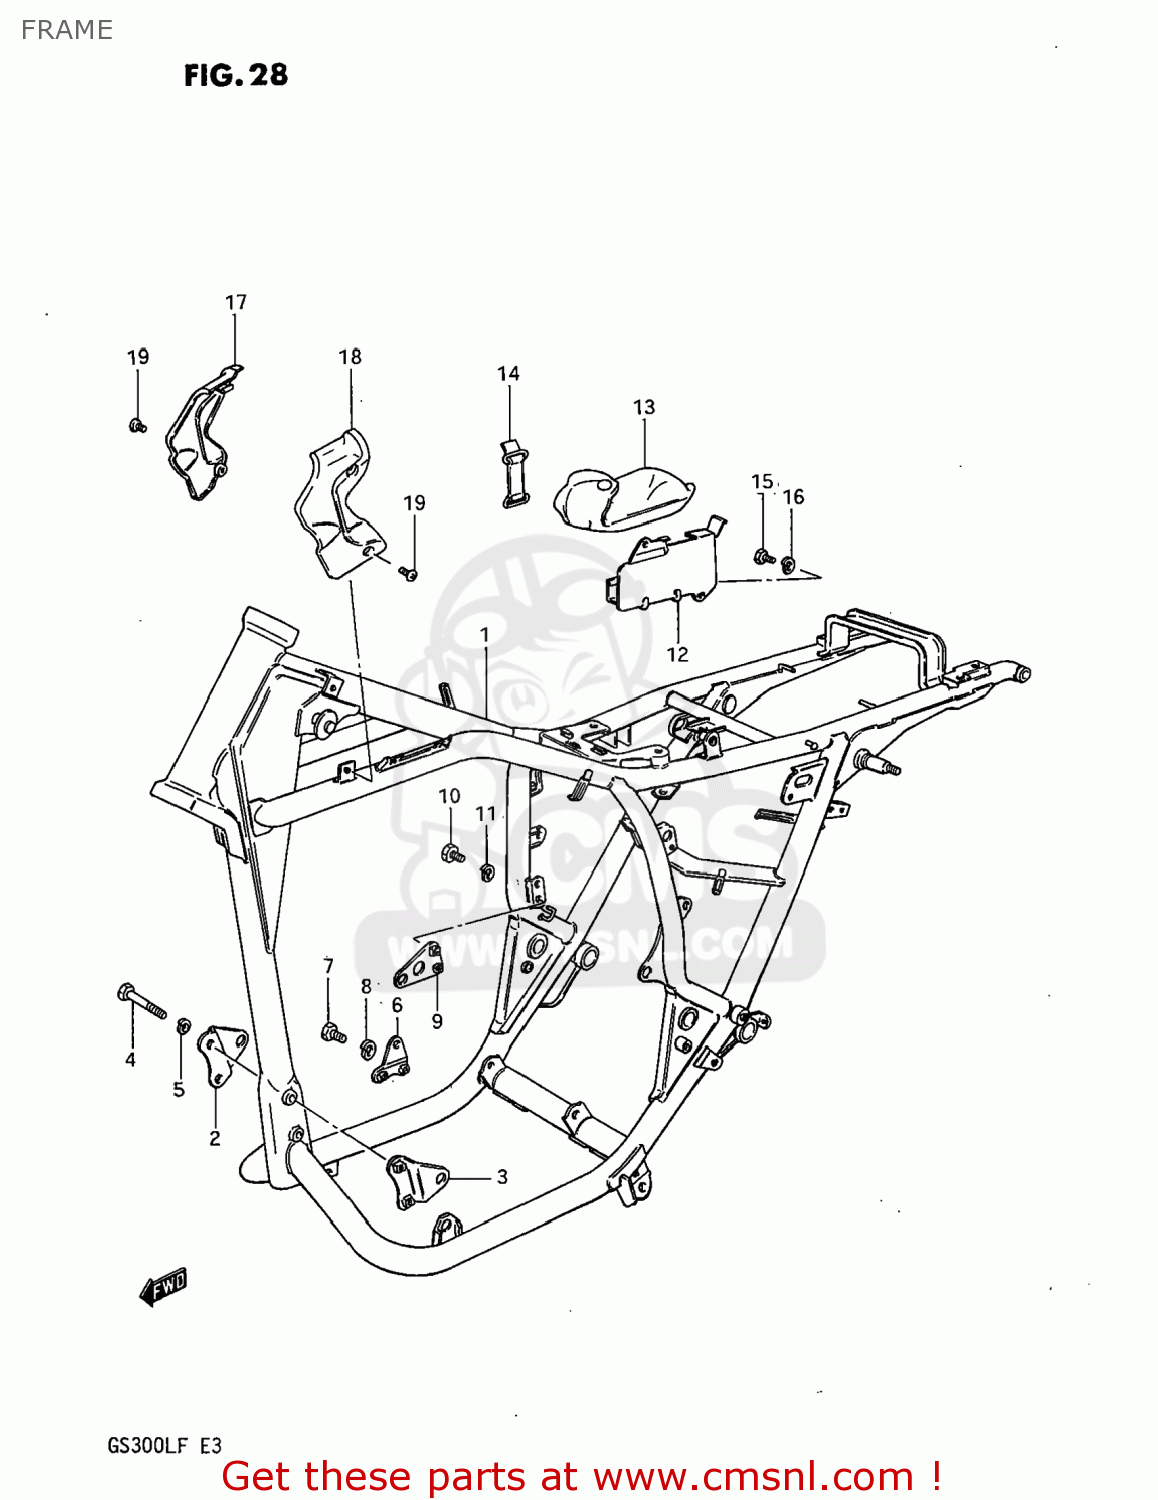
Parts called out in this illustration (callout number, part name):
1	FRAME
2	PLATE,MOUNTING NO.1,RIGHT
3	PLATE,ENGINE MOUNTING
4	BOLT, LOWER
5	WASHER,LOCK,8.
6	PLATE,MOUNTING NO.2,LEFT
7	BOLT
8	WASHER,LOCK,8.
9	PLATE,MOUNTING NO.4,LEFT
10	BOLT
11	WASHER,LOCK,8.
12	HOLDER,TOOL
13	TOOL SET
14	BAND
15	BOLT
16	LOCK WASHER
17	COVER,FRAME HEAD,RIGHT
18	COVER,FRAME HEAD,LEFT
19	SCREW
